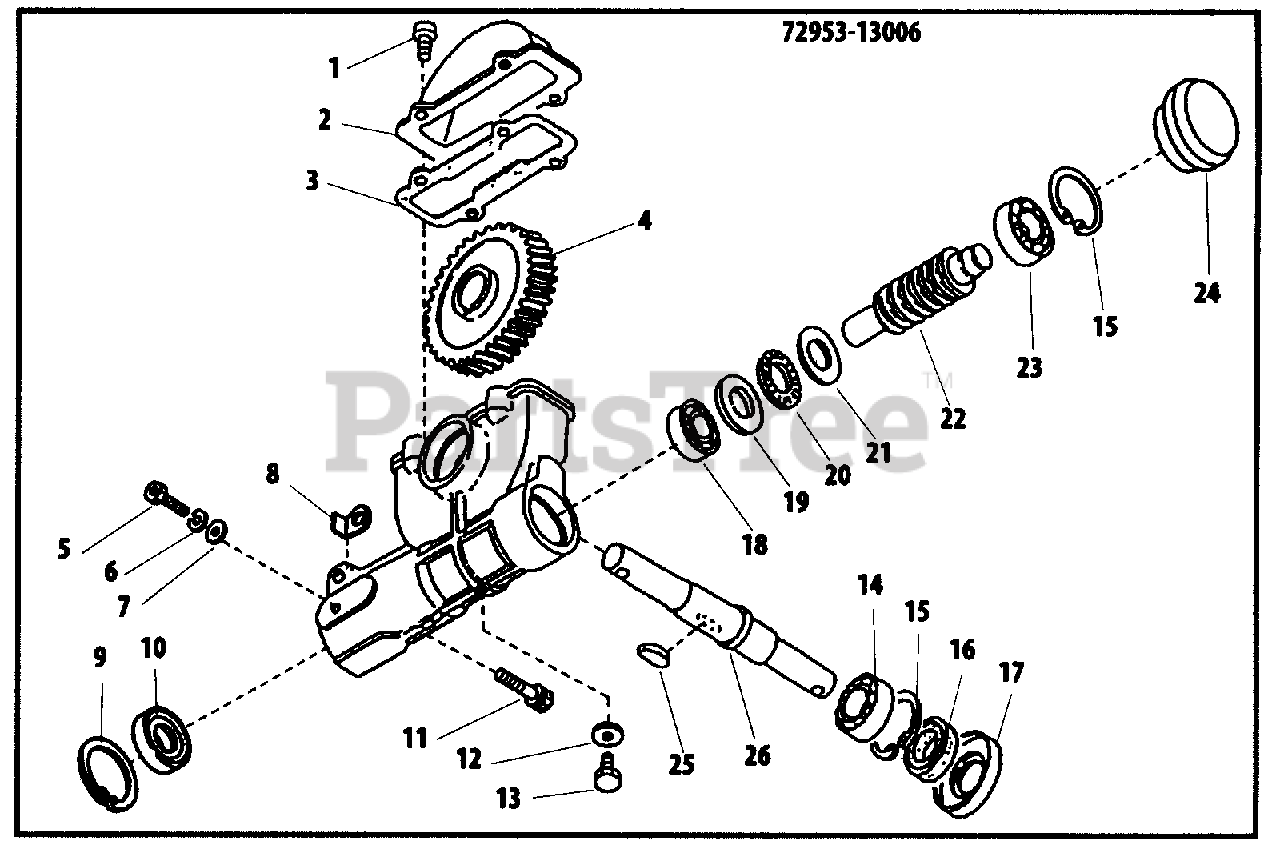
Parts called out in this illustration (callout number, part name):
1	SCREW - 5X14
2	COVER, GEAR CASE
3	GASKET
4	GEAR - WORM
5	SCREW - 5X12
6	LOCKWASHER - 5
7	WASHER - 5
9	RING, RETAINING - 22
10	SEAL, OIL
11	SCREW - 6X30
14	BEARING, BALL - 6902
15	RING, RETAINING - 28
16	SEAL, OIL
18	BEARING, BALL - 6901
19	WASHER, THRUST
20	BEARING, NEEDLE
21	WASHER, THRUST
22	BEARING, NEEDLE
23	BEARING, BALL - 6001
24	CAP
26	DRIVESHAFT
